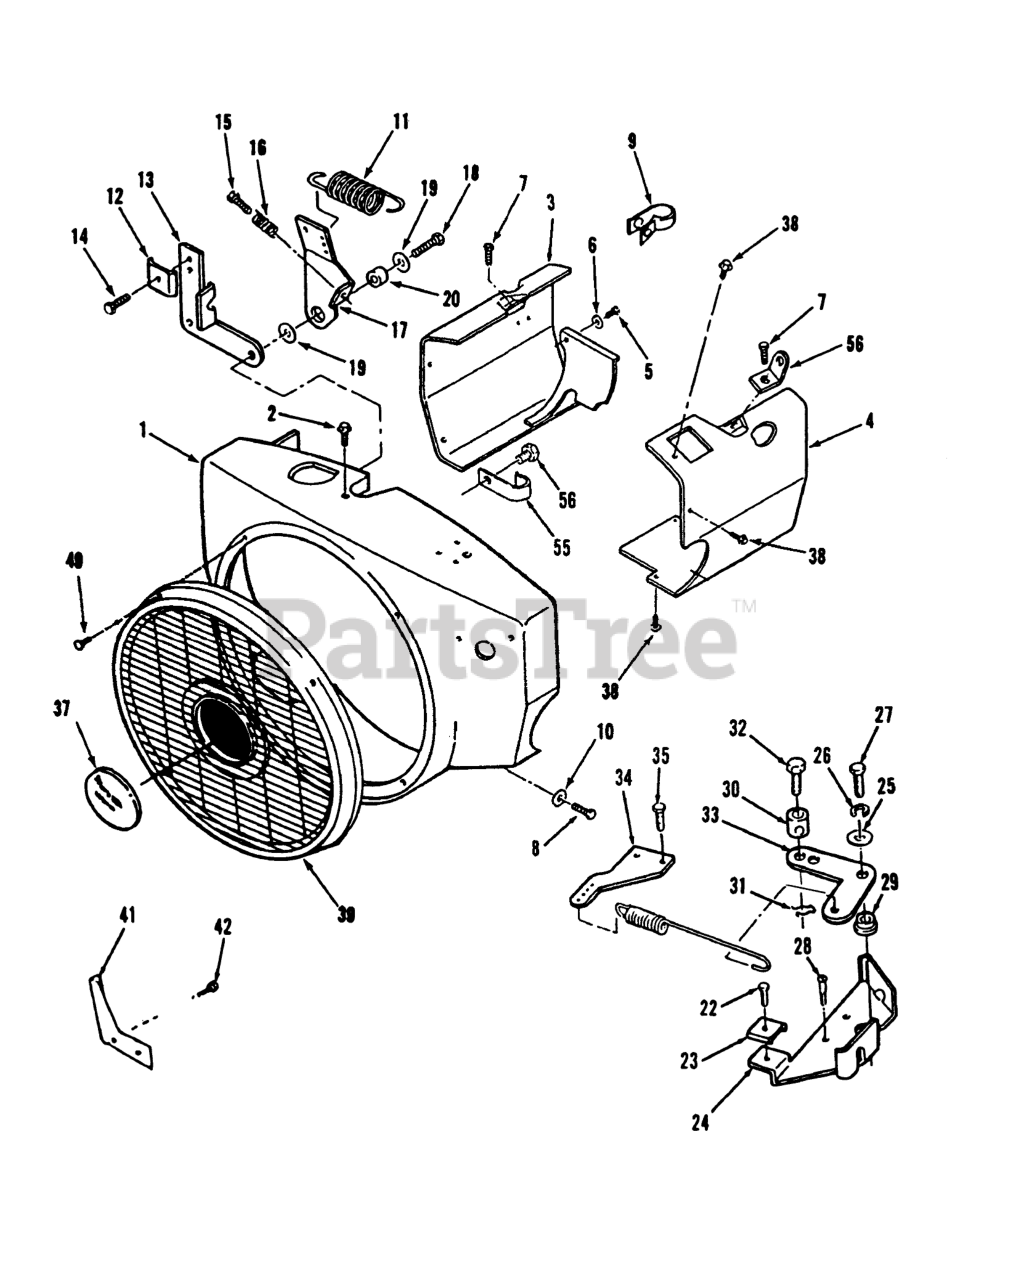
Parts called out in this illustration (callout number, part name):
1	HOUSING
2	HEX HD CAPSCREW
3	LH AIR CYLINDER HSG
4	RH AIR CYLINDER HSG
5	SCREW-HH
6	Clamp
7	SCREW-HWH
8	Bolt
9	Clamp
10	Washer
11	Spring
13	BRACKET
14	Bolt
15	SCREW-TAP
16	Spring
17	GOVERNOR CONTROL ARM
18	SCREW-HWH
19	Screw
20	Bushing
22	TAPPING HEX HD CS
24	BRKT-GOVERNOR CONTRL
25	WASHER-FLAT
26	WASHER-LOCK, SPRING
27	SCREW - CAP HEX HEAD
28	HEX HD CAP SCREW
29	BUSHING-GOV CONTROL
30	Oil Seal
31	PIN-COTTER
32	Bolt
33	LINK-GOV CONTROL
34	ADAPTER-GOV ARM
35	SCREW-TAPPING PAN HD
37	SCREW-HWH
38	Bolt
39	GUARD-STATIONARY
41	BRACKET
42	SCREW - THREAD CUTTING
49	SCREW-PAN HEAD
55	Clip
56	Bracket-Lifting
